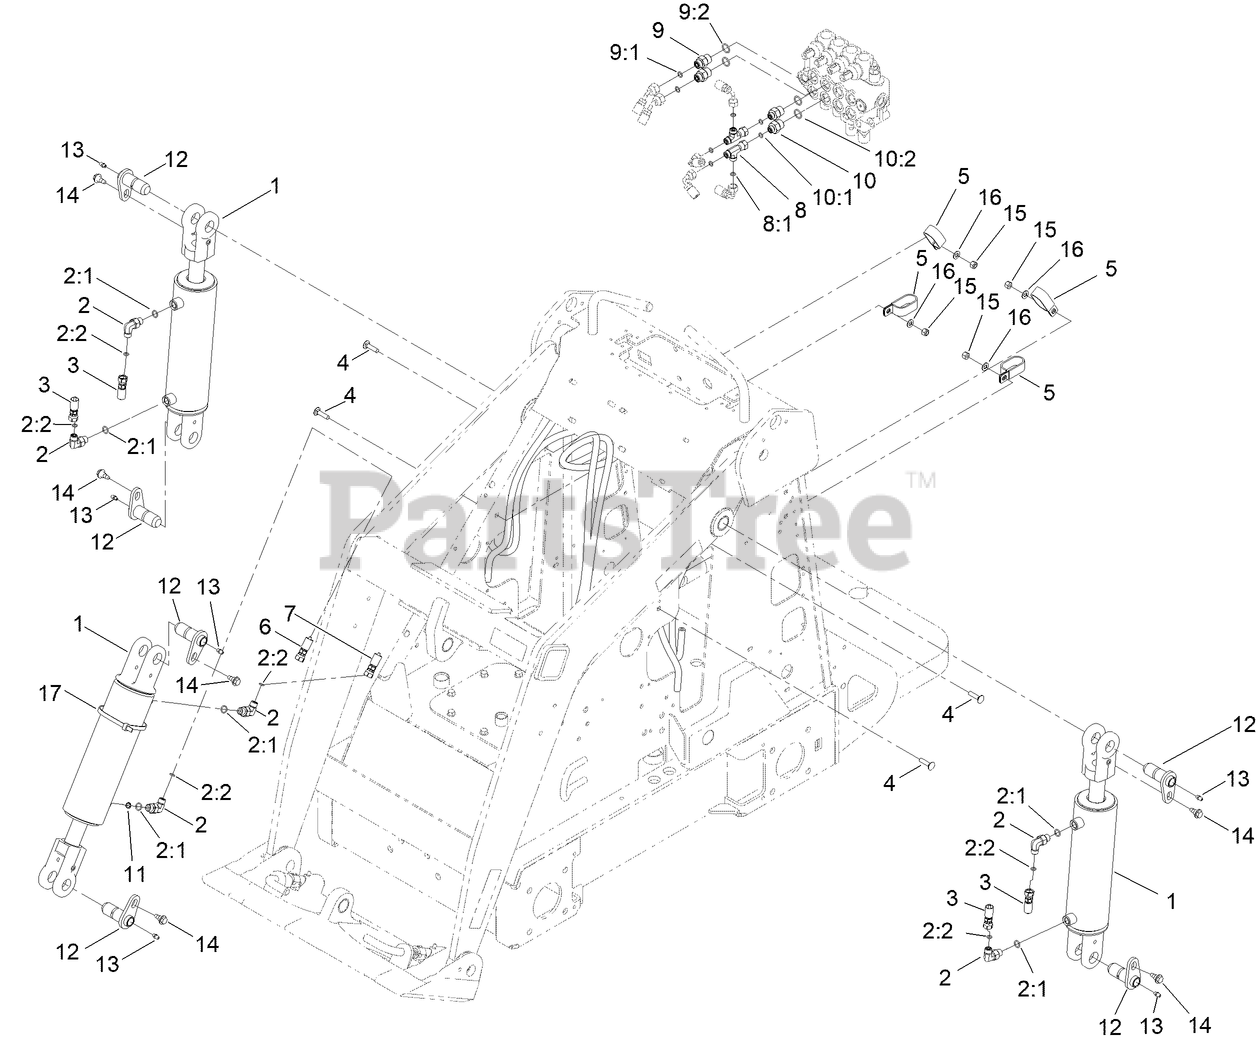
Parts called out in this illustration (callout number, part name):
1	CYLINDER-HYDRAULIC
2	FITTING-ELBOW, 90 DEG
2:1	O-RING
2:2	O-RING
3	HOSE-HYD
4	SCREW-CARR
5	CLAMP-R, DOUBLE
6	HOSE-HYD
7	HOSE-HYD
8	FITTING-HYD
8:1	O-RING
9	FITTING-STRAIGHT
9:1	O-RING
9:2	O-RING
10	FITTING-STR
10:1	O-RING
10:2	O-RING
11	ORIFICE-PORT INSERT, ONE WAY
12	PIN-PIVOT
13	FITTING-GREASE
14	BOLT-SHOULDER
15	NUT-LOCK, NI
16	WASHER-PLAIN
17	TIE-CABLE
